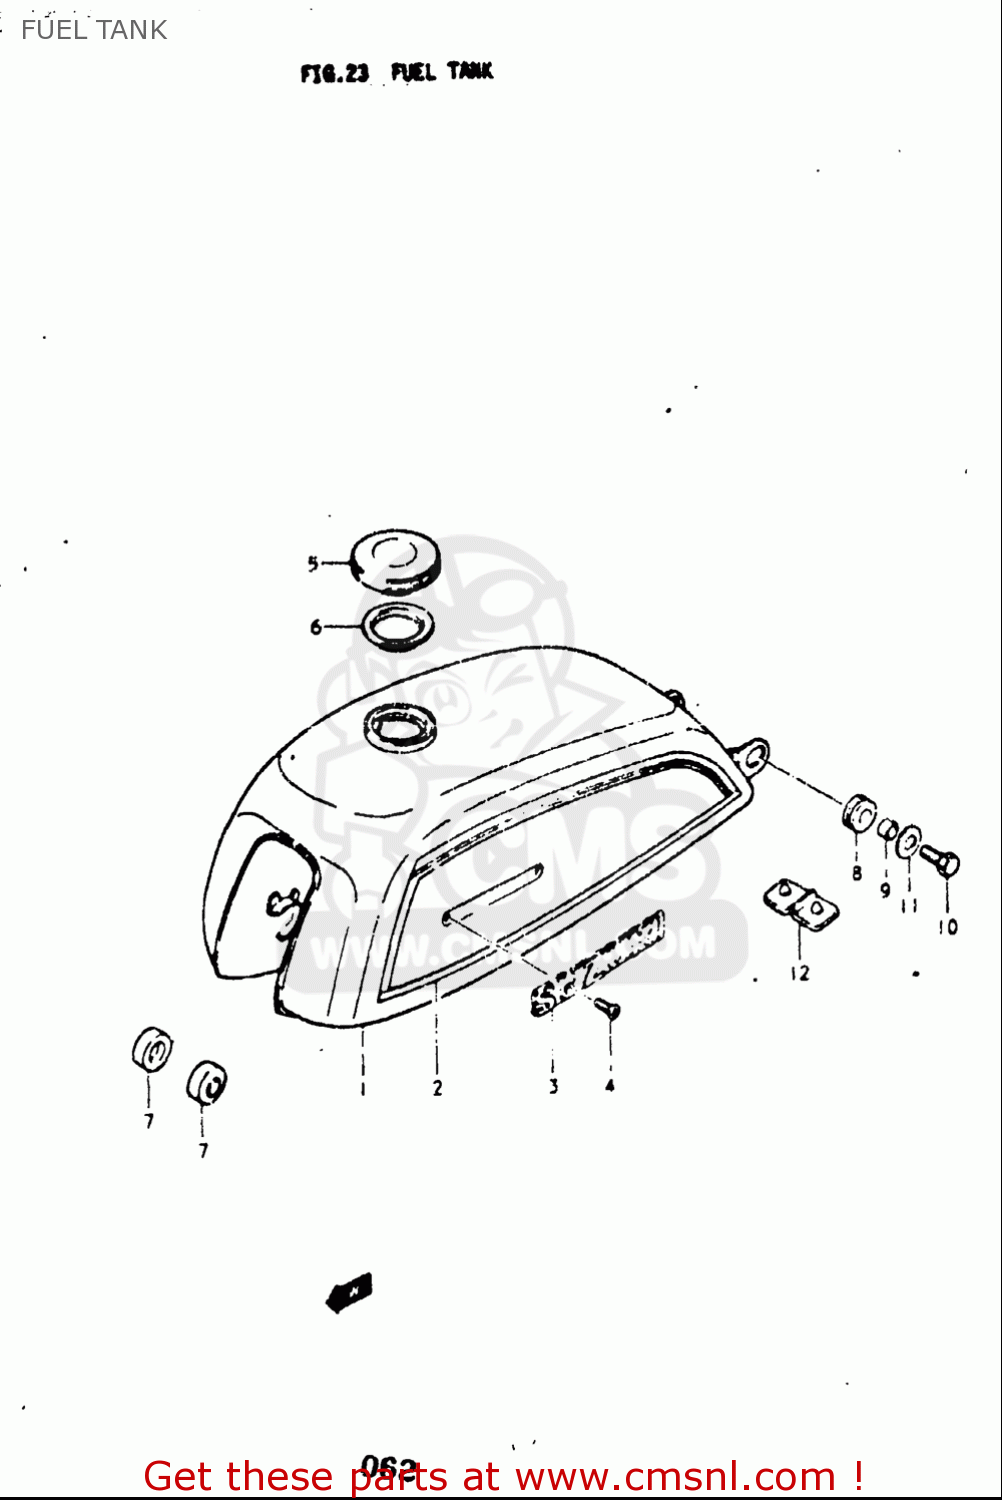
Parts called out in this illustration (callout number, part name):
1	TANK ASSEMBLY,FUEL
3	EMBLEM,FUEL TANK
4	SCREW
5	CAP ASSY,FUEL TANK FILLER
6	GASKET (NAS)
7	CUSHION
8	CUSHION
9	SPACER(6.5X10X7)
10	BOLT
11	WASHER(6.5X24X1.6)
12	CUSHION
